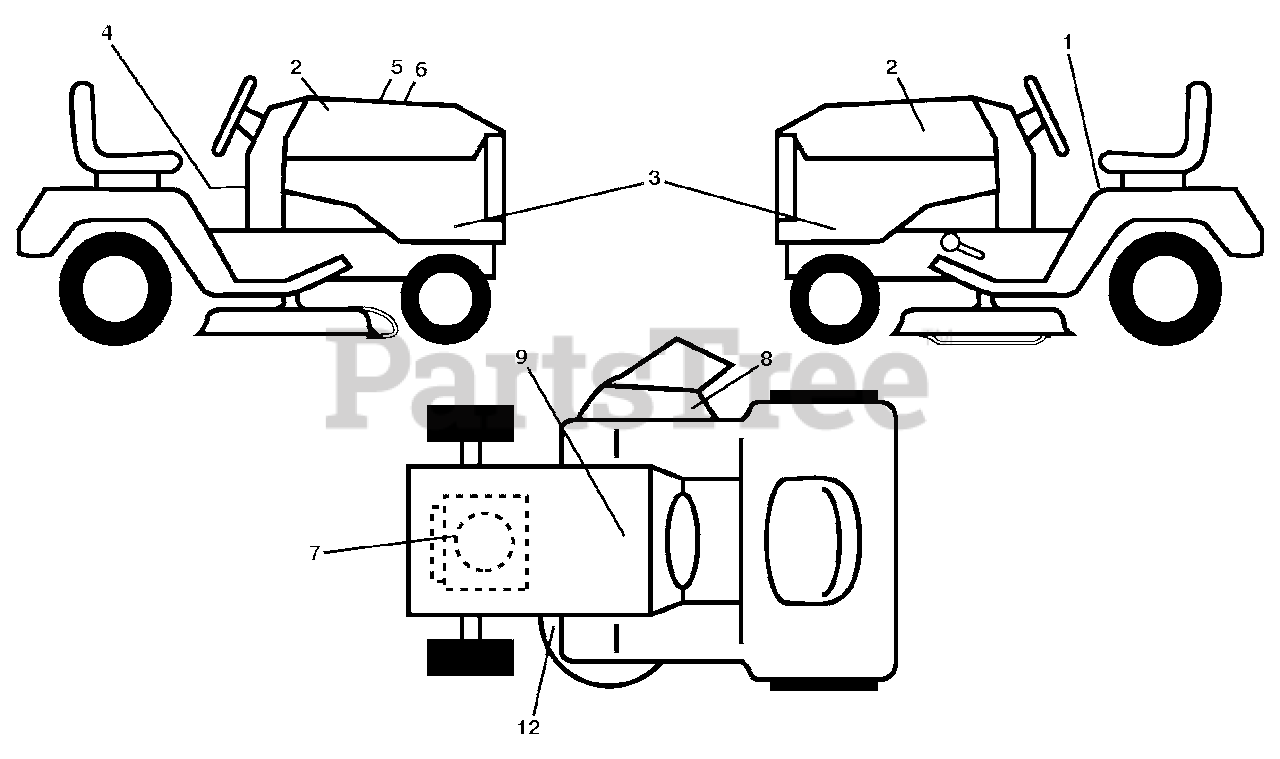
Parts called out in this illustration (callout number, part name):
1	DECAL.FENDER.WARNING.ENGLISH
2	DECAL.BADGE.170MM.TEXTLOGO.
3	DECAL.SIDE.PANEL.YTH22V46.2013
4	DECAL, WARNING SPARK ARRESTOR
5	DECAL.WARNING.CUST.RESP.E85.
6	DECAL.RPL.BSM.44.INTK.TLW.46
7	DECAL.ENG.BS.22HP.INTK
8	DECAL.MOWER.WARN.KEEP.HAND.AWY
9	DECAL BTRY SYMBOLS
12	DECAL.V-BELT.SCH.42/46"MEC/ELE
